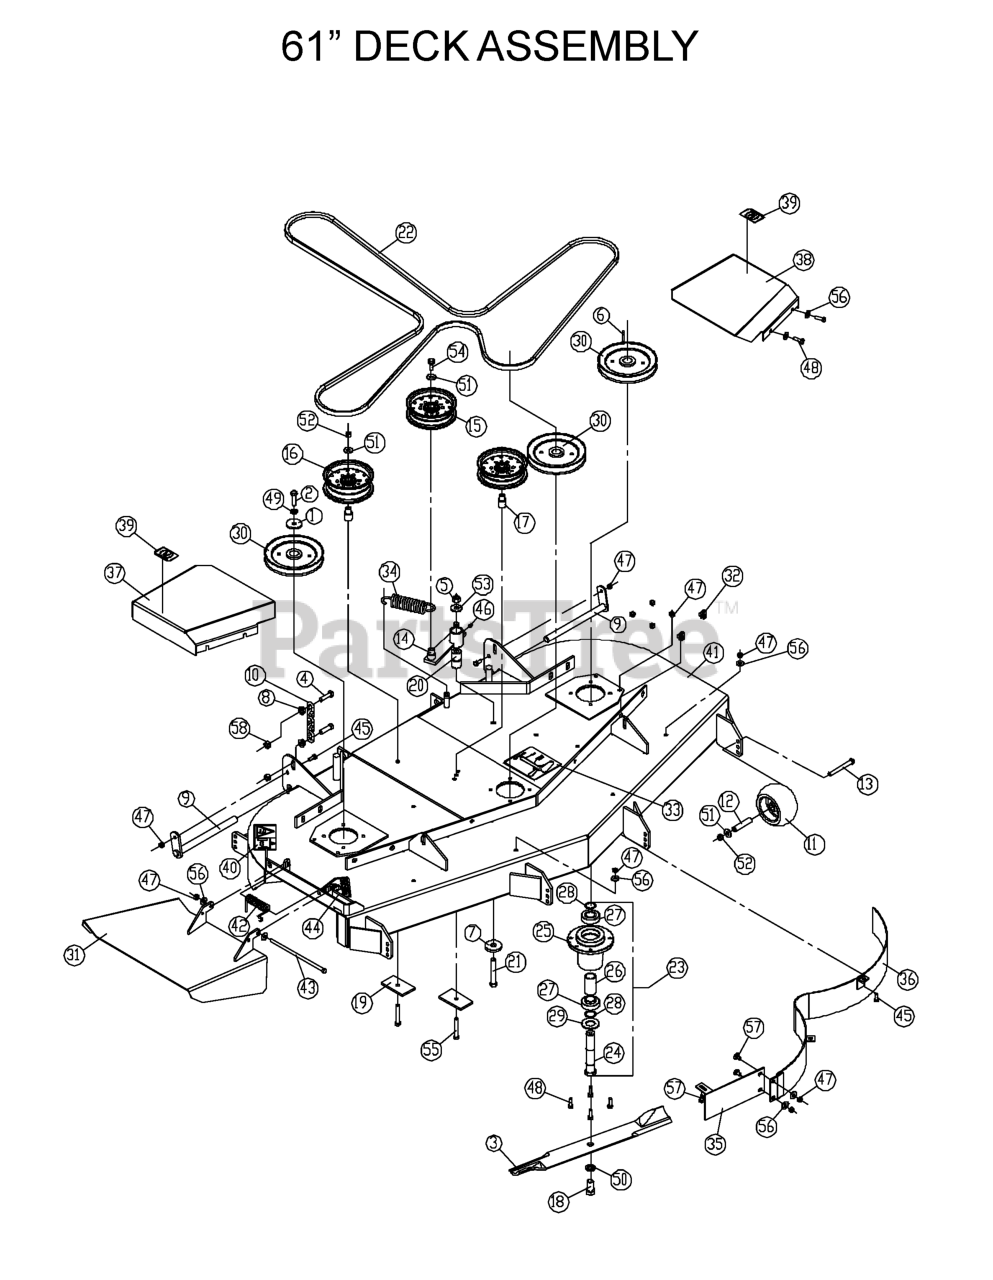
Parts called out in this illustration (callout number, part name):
1	SPINDLE WASHER
2	HCS 7/16F X 1 1/2
3	BLADE OEM 21" (61" DECK)
4	HCS 7/16C X 1 1/2
5	NUT 1/2-13 HEX NYLOC ZD
6	KEY 1/4 SQ X 1 1/8
7	WASHER, SUPPORT
8	NUT 7/16C WHIZ
10	LIFT CHAIN
11	ANTI-SCALP ROLLER
13	HCS 3/8C X 3 1/2
15	IDLER PULLEY
16	IDLER PULLEY (TALL)
17	IDLER BUSHING
18	HCS 5/8F X 1 1/4
19	SUPPORT PLATE
20	PIVOT BUSHING
21	HCS 1/2C X 3 1/4
22	DECK BELT 61
23	HOUSING ASM.
25	HOUSING, DIE CAST
27	BEARING
28	BUSHING.MACHINE.18.GAUGE
29	MACHINERY BUSHING 10 GA.
31	DISCHARGE CHUTE
32	U-CLIP 5/16-18 NUT RETAINER
33	DECAL, BELT ROUTING
34	DECK SPRING
35	CENTER BAFFLE - 61
36	MAIN BAFFLE - 61" BLK
37	SHIELD, BELT 61-ORANGE
38	SHIELD, BELT 61-ORANGE
39	DECAL, NO STEP
40	DECAL, EURO SEVERING
42	SPRING, TORTION
43	HCS 5/16-18 X 8-1/2 GR 5 ZD
44	DECAL, CPSC
45	HCS 5/16C X 3/4
46	ZERK
47	NUT 5/16C CENTERLOCK
48	HCS 5/16C X 1
49	WASHER 7/16 LOCK
50	LOCKWASHER 5/8
51	WASHER 3/8 FLAT
52	NUT 3/8C CENTERBLOCK
53	WASHER 1/2 FLAT
54	4CS 3/8C X 1 SERRATED HEAD
55	HCS 3/8C X 2 1/2
56	WASHER 5/16 FLAT
57	CARRIAGE BOLT 5/16C X 5/8"
58	NUT 7/16C CENTERLOCK
